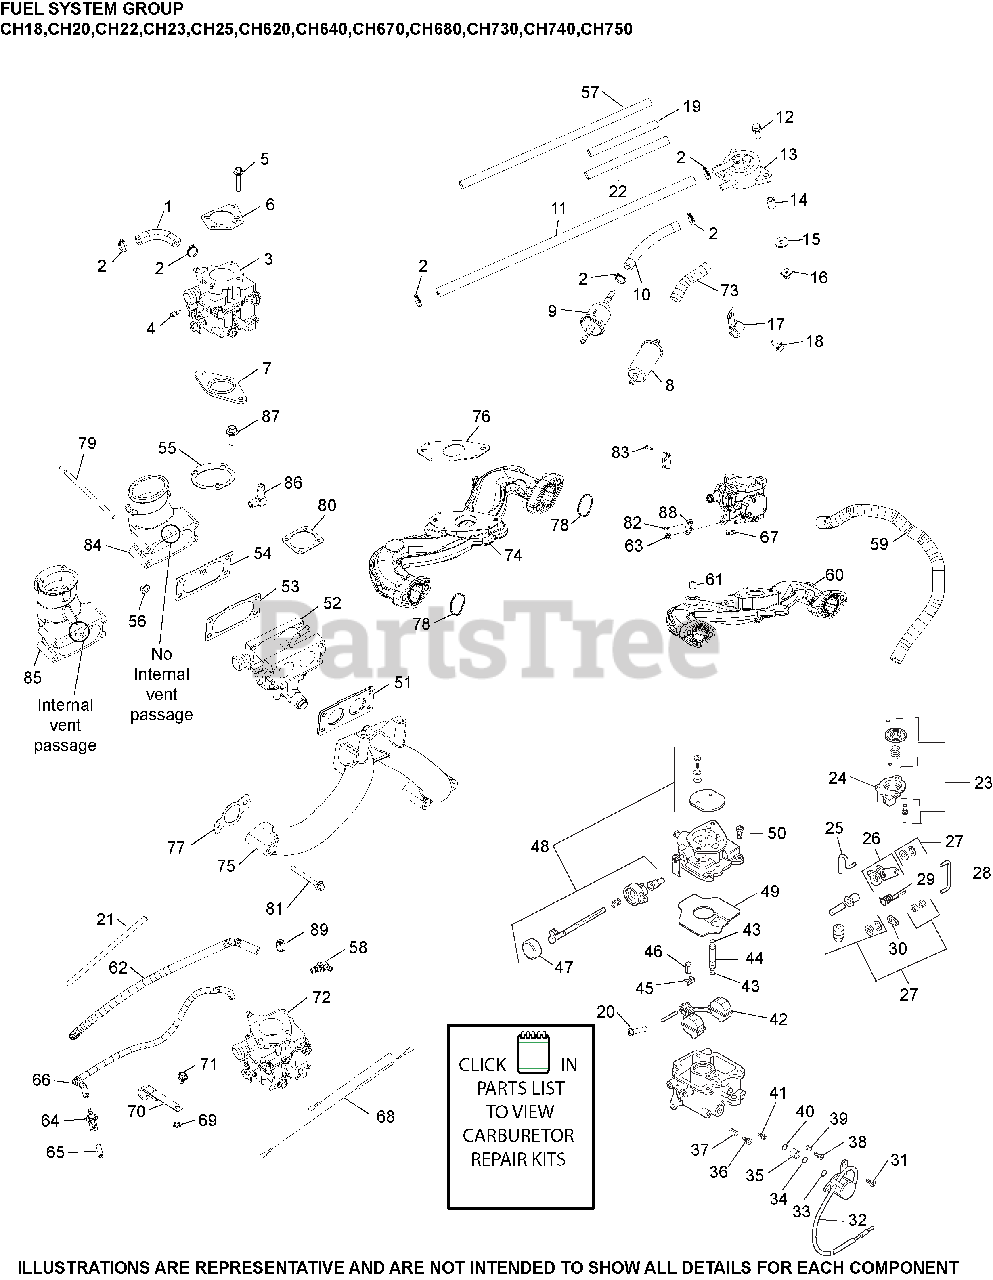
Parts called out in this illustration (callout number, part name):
1	HOSE,LW PERM.FUEL 24.00"-USE 25 111 81-S
3	KIT, CARBURETOR W/GASKETS
4	SCREW, THROTTLE STOP
5	SCREW, FLG M6X1.0X25
6	GASKET, AIR CLEANER BASE
9	FILTER, FUEL
32	KIT, SOLENOID
42	KIT, REPAIR FLOAT
48	KIT, REPAIR CHOKE
62	SLEEVE, ANTI-ABRASION
64	CONNECTOR, EVAPORATIVE
65	CAP, MASKING
66	HOSE, EVAPORATIVE 20"
74	KIT, INTAKE MANIFOLD
76	GASKET, CARBURETOR
78	O-RING, INTAKE PORT
